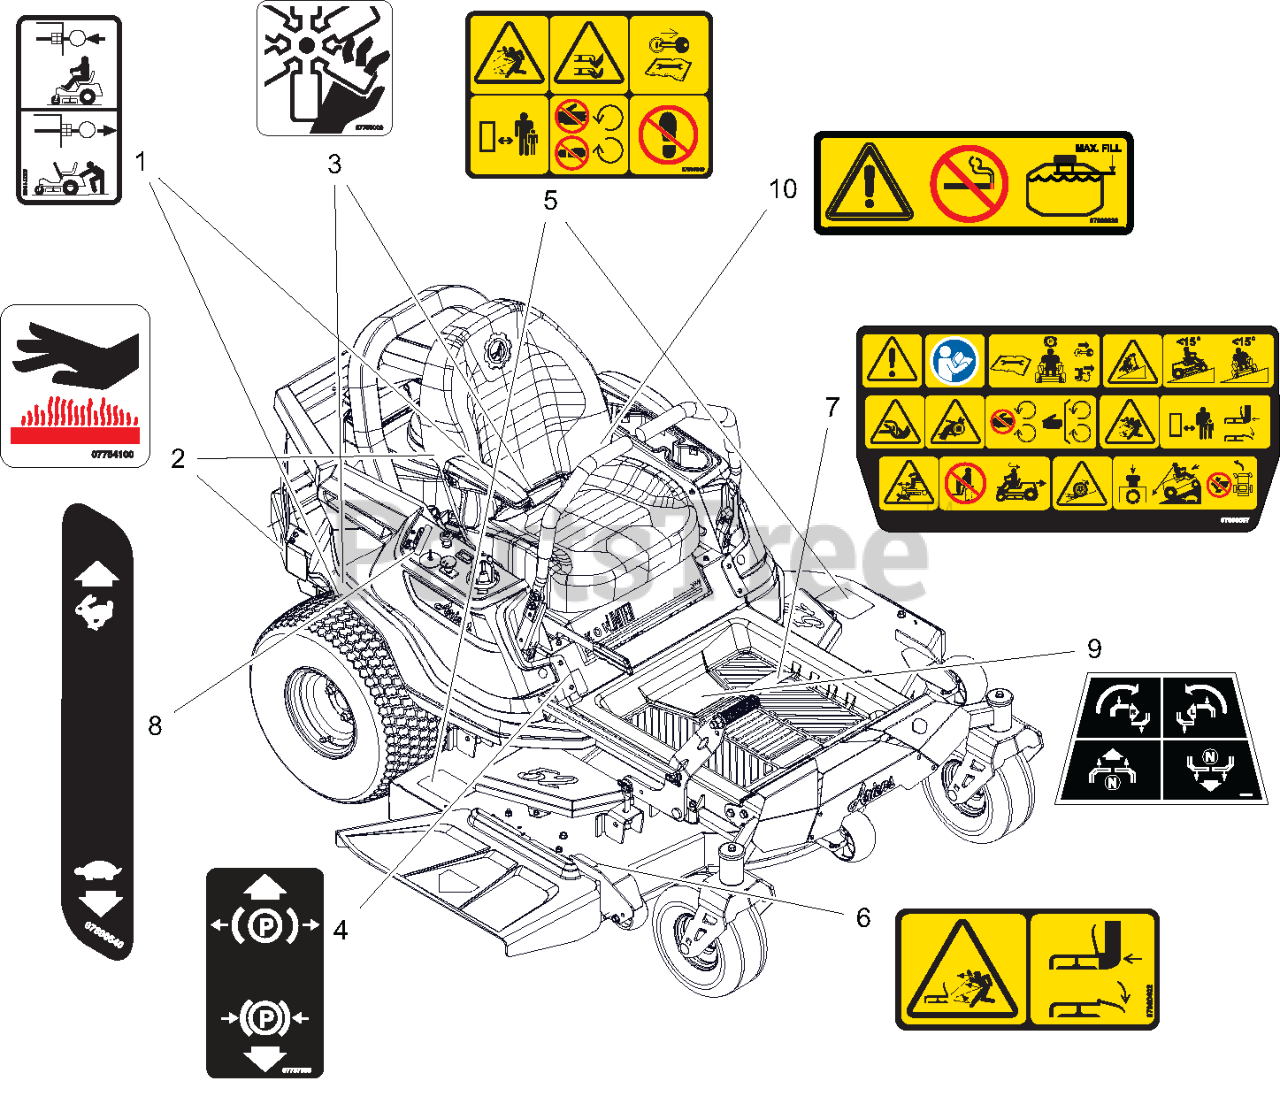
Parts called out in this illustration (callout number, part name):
1	DECAL, TRANSMISSION DISCONNECT
2	DECAL, HOT SURFACE
3	DECAL, DANGER FAN
4	DECAL, PARKING BRAKE LEVER
5	DECAL, SAFETY - MOWER DECK
6	DECAL, SAFETY - DECK GUARDING
7	DECAL, MAIN SAFETY
8	DECAL, DASH DECAL
9	DECAL, STEERING
10	DECAL, FUEL WARNING
